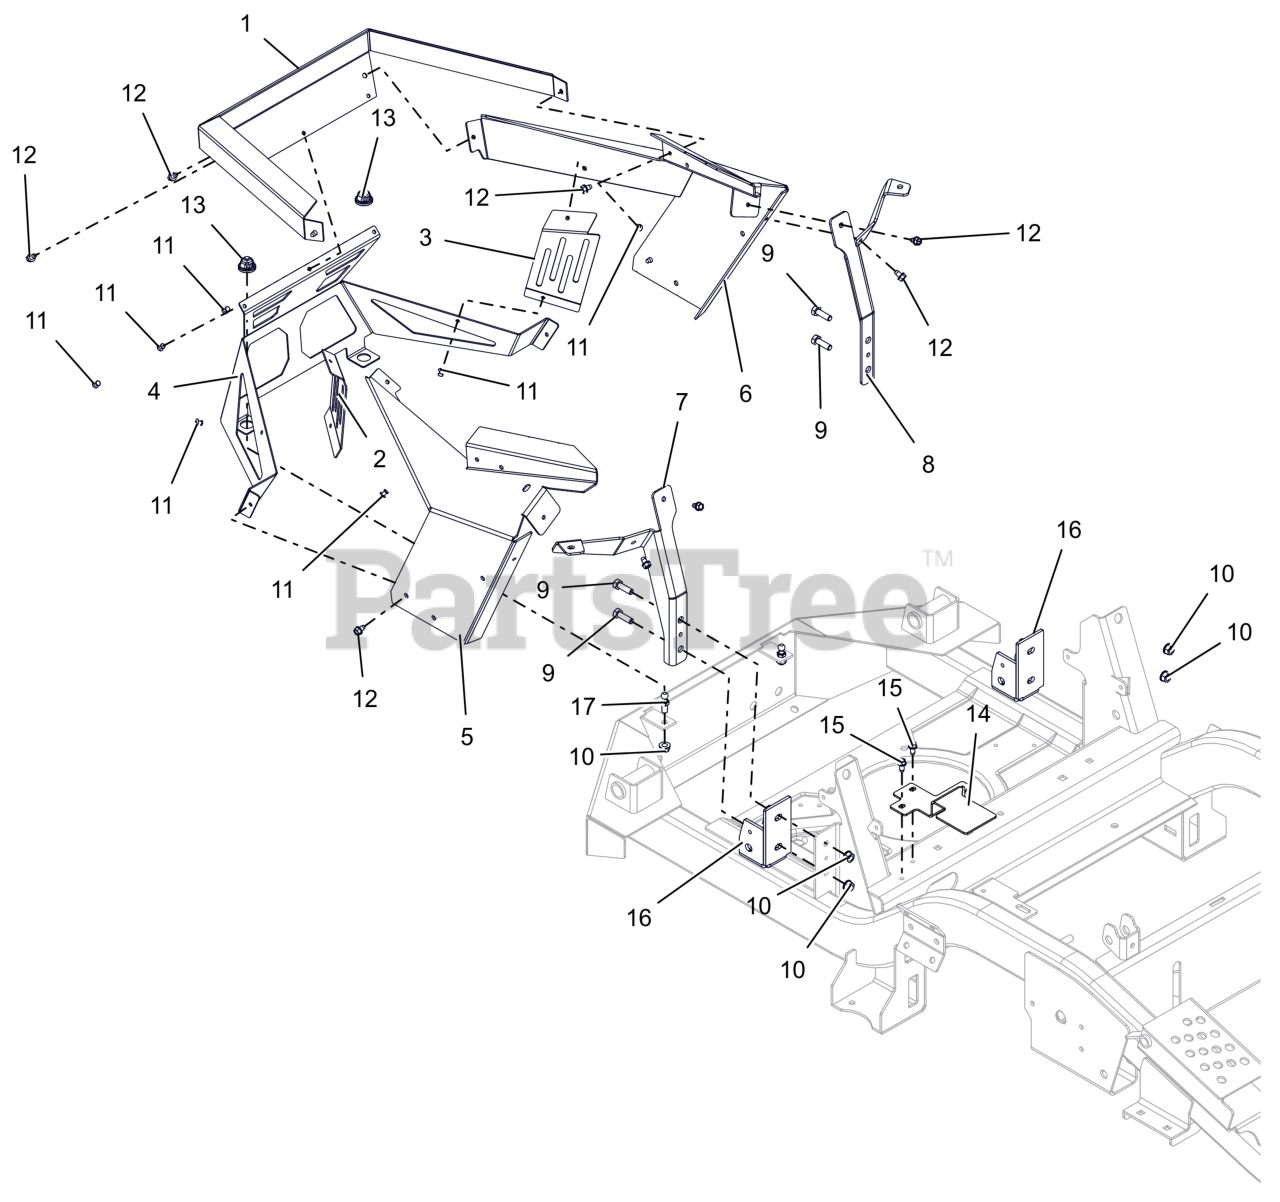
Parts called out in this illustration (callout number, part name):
1	GUARD,ENGINE WRAP
2	SHIELD,RH ENGINE GUARD VALVE
3	SHIELD,LH ENGINE GUARD VALVE
4	GUARD, ENGINE
5	PANEL, RH REAR FENDER MOUNT
6	PANEL, LH REAR FENDER MOUNT
7	BRKT, RH FENDER MTG (ORANGE)
8	BRKT, LH FENDER MOUNT (ORANGE)
9	BLT, HEX .31-18X1.00 G8 ZCC
10	NUT,LK-CTR-FLG .31-18 GF ZCC
11	RIVET, .1875 AL/AL .126-.250
12	SCR,TAP .25-20X.375 HWH TR ZCC
13	GROMMET, 10MM BOLLHOFF
14	GUARD, TRANSAXLE FAN RH (BLACK)
15	SCR-TAP .25-20X.50 HWH ZCC
16	BRKT, ROPS SUPPORT (BLACK)
17	STUD- BALL
